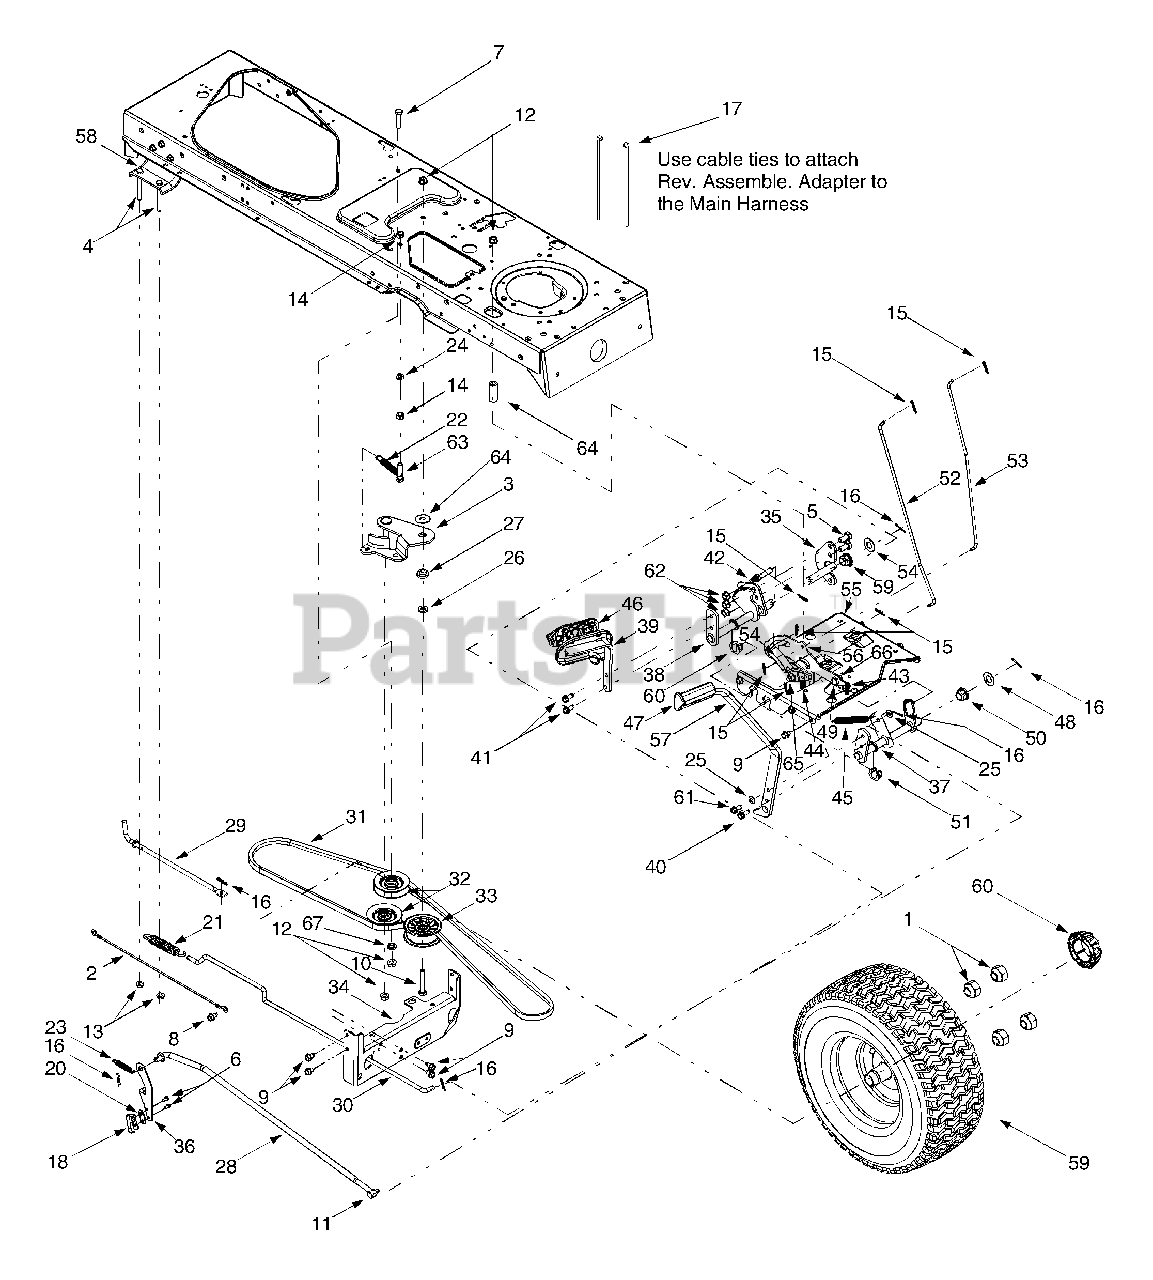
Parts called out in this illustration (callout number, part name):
1	Lug Nut, 3/4-16
2	Reverse/Grnd Wire Harness Adptr.
4	Hex Cap Screw, 5/16-18 x 2.75
5	Hex Cap Screw, 3/8-16 x.75
6	Screw, #8-18 x.5
7	Hex Cap Screw, 3/8-16 x 1.5
8	Self-tapping Screw, 1/4-20 x.50
9	Self-tapping Screw, 5/16-12 x.75
10	Hex Cap Screw, 3/8-16 x 2.25
11	Ferrule, 3/8-24
12	Flange Lock Nut, 3/8-16
13	Flange Lock Nut, 5/16-18
14	Hex Nut, 3/8-16
15	Internal Cotter Pin
16	Cotter Pin
17	Cable Tie
18	Short Spring Switch
20	Insulator Nut Plate
21	Extension Spring,.59 x 4.0
22	Extension Spring,.5 x 3.97
23	Extension Spring, 3/8 x 1.44
24	Lock Washer, 3/8
25	Flat Washer,.344 x.750 x.120
26	Flat Washer,.407 x.812 x.135
27	Shoulder Spacer,.38
28	Hydrostatic Control Rod
29	Hydrostatic Bypass Rod
30	Hydrostatic Brake Rod
31	Drive Belt
32	V-idler Pulley, 3.06
33	Flat Idler Pulley, 2.75
40	Self-tapping Screw, 5/16-18 x.875
41	Self-tapping Screw, 5/16-18 x.75
42	Pin, 3/8-16 x 2.43
43	Compression Spring,.40 OD x 1.17
44	Extension Spring,.50 OD x 1.41
45	Extension Spring,.50 OD x 6.37
46	Drive Pedal Pad
47	Brake Pedal Pad
48	Flat Washer,.64 x 1.24 x.06
49	Shoulder Screw,.437 x 1.62
50	Hex Flange Bearing
51	Split Hex Flange Bearing
52	Cruise Control Rod
53	Brake Lock Control Rod
54	Cruise Latch
56	Drive Lockout Bracket
60	Hub Cap
61	Self-tapping Screw, 5/16-18 x.75
62	Flange Lock Nut 3/8-16
63	Hex Cap Screw, 3/8-16 x 1.5
64	Flat Washer.38 x 1.38 x.125
65	Shoulder Screw 3/8-16.50 x.27
66	Flange Lock Nut, 5/16-18
67	Spacer .38 x .625 x .21
